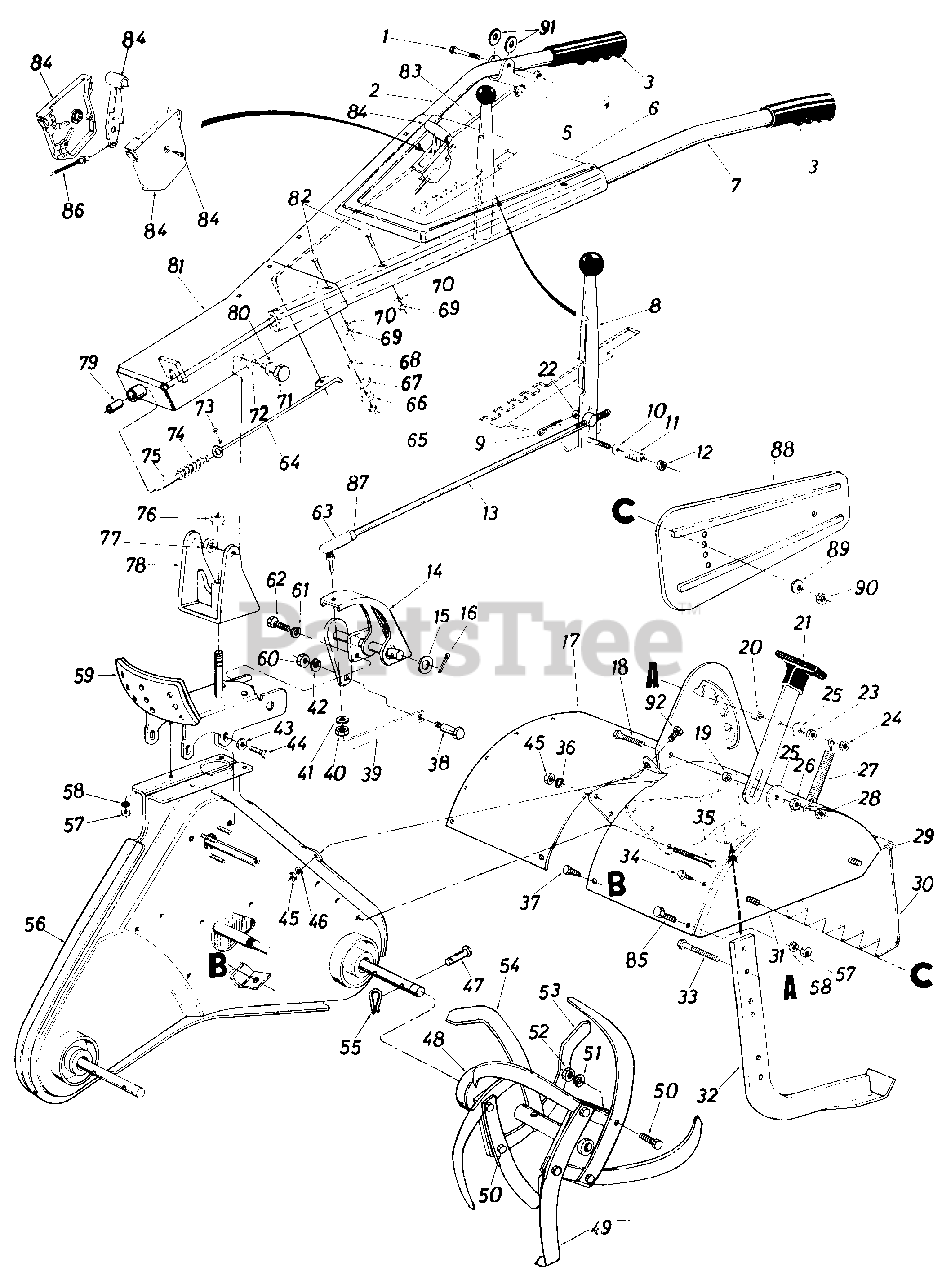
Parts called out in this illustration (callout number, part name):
1	Hex Bolt 1/4-20 x 1.75" Lg.
2	Handle - R.H.
3	Grip
4	Hex Cent. L-Nut 1/4-20 Thd.
5	Clutch Grip
6	Handle Panel Ass'y.
7	Handle - L.H.
8	Clutch Handle Ass'y.
9	Hairpin Cotter
10	Belleville Wash. .38" I.D.
11	Compression Spring .88" O.D. x .81" Lg.
12	Hex Cent. L-Nut 3/8-24 Thd.
13	Gear Shift Rod
14	Pivot Horn Ass'y.
15	Fl-Wash. .630 I.D. x 1.0" O.D. x .063
16	Cotter Pin 1/8" Dia. x .75" Lg.
17	Tine Shield Ass'y.
18	Hex Bolt 3/8-16 x 1.5" Lg.
19	Spacer .38 I.D. x .50 O.D. x .18 Lg.
20	Spacer .38 I.D. x .50 O.D. x .38 Lg.
21	Depth Bar Handle Ass'y. w/Knob
22	Ferrule
23	Hex Nut 3/8-16 Thd.
24	Hex Ins. L-Nut 3/8-16 Thd.
25	Fl-Wash. .38 I.D. x 1.50 O.D. x .13
26	Hex Nut 3/8-16 Thd.
27	Spring - Depth Bar
28	Hex Ins. L-Nut 3/8-16 Thd.
29	Hinge Rod
30	Tine Shield Hinge Flap Ass'y.
31	Side Cover Tine Shield - L.H.
32	Depth/Drag Bar Ass'y.
33	Hex Bolt 3/8-16 x 1.75" Lg.
34	Hex Wash. Hd. Self-Tap Scr. 5/16-18 x .62" Lg.
35	Hex Bolt 3/8-24 x 3.0" Lg.
36	L-Wash. 3/8" I.D.
37	Hex Wash. Hd. Self-Tap Scr.
38	Shoulder Bolt .50" Dia. x .25" Lg.
39	Control Bracket
40	Hex Ins. L-Nut 3/8-24 Thd.
41	L-Wash. 3/8" I.D.
42	L-Wash. 3/8" I.D.
43	Belleville Wash.
44	Hex Wash. Hd. Self-Tap Scr.
45	Hex Nut 3/8-24 Thd.
46	L-Wash. 3/8" Scr.
47	Clevis Pin
48	Tine Adapter Ass'y.
49	L.H. Tine Ass'y. Comp.
50	Hex Bolt 3/8-24 x 1.25" Lg.
51	L-Wash. 3/8" I.D.
52	Hex Nut 3/8-24 Thd.
54	Tine - L.H.
55	Hairpin Cotter
56	Chain Case Ass'y. Comp.
57	Hex Nut 5/16-18 Thd.
58	L-Wash 5/16" I.D.
59	Handle Positioner Ass'y.
60	Hex Ins. L-Nut 3/8-16 Thd.
61	L-Wash. 5/16" I.D.
62	Hex Wash. Hd. Self-Tap Scr.
63	Rod End 3/8-24 Thd.
64	Lower Handle Control Rod
65	Hex Nut 5/16-18 Thd.
66	Pivot Handle Brg.
67	Pivot Handle Link
68	Bushing Wash.
69	Hex Nut 5/16-18 Thd.
70	L-Wash. 5/16" I.D.
71	Shld. Bolt .500" Dia. x .660
72	Belleville Wash. .505" I.D. x 1.00" O.D.
73	Cotter Pin 1/8" Dia. x .75" Lg.
74	Compression Spring
75	Locking Pin
76	Hex Ins. L-Nut 5/8-16 Thd.
77	Hex Top L-Nut 3/8-16 Thd.
78	Pivot Brkt. Ass'y.
79	Sleeve Brg. .50" I.D. x .62" O.D. x 1.12" Lg.
80	Fl-Wash. .50" I.D. x 1.00" O.D. x .090
81	Handle Mtg. Brkt. Ass'y.
82	Carriage Bolt 5/16-18 x 1.75" Lg.
83	Handle Lock Rod
84	Throttle Control Box Ass'y.
85	Hex Bolt 5/16-18 x .75" Lg.
86	Throttle Control Wire
87	Hex Jam Nut 3/8-24 Thd.
90	Hex Nut 5/16"-18 Thd.
91	Fl-Wash. 1/4" I.D.
92	Hex Bolt 3/8-24 x .75" Lg.
